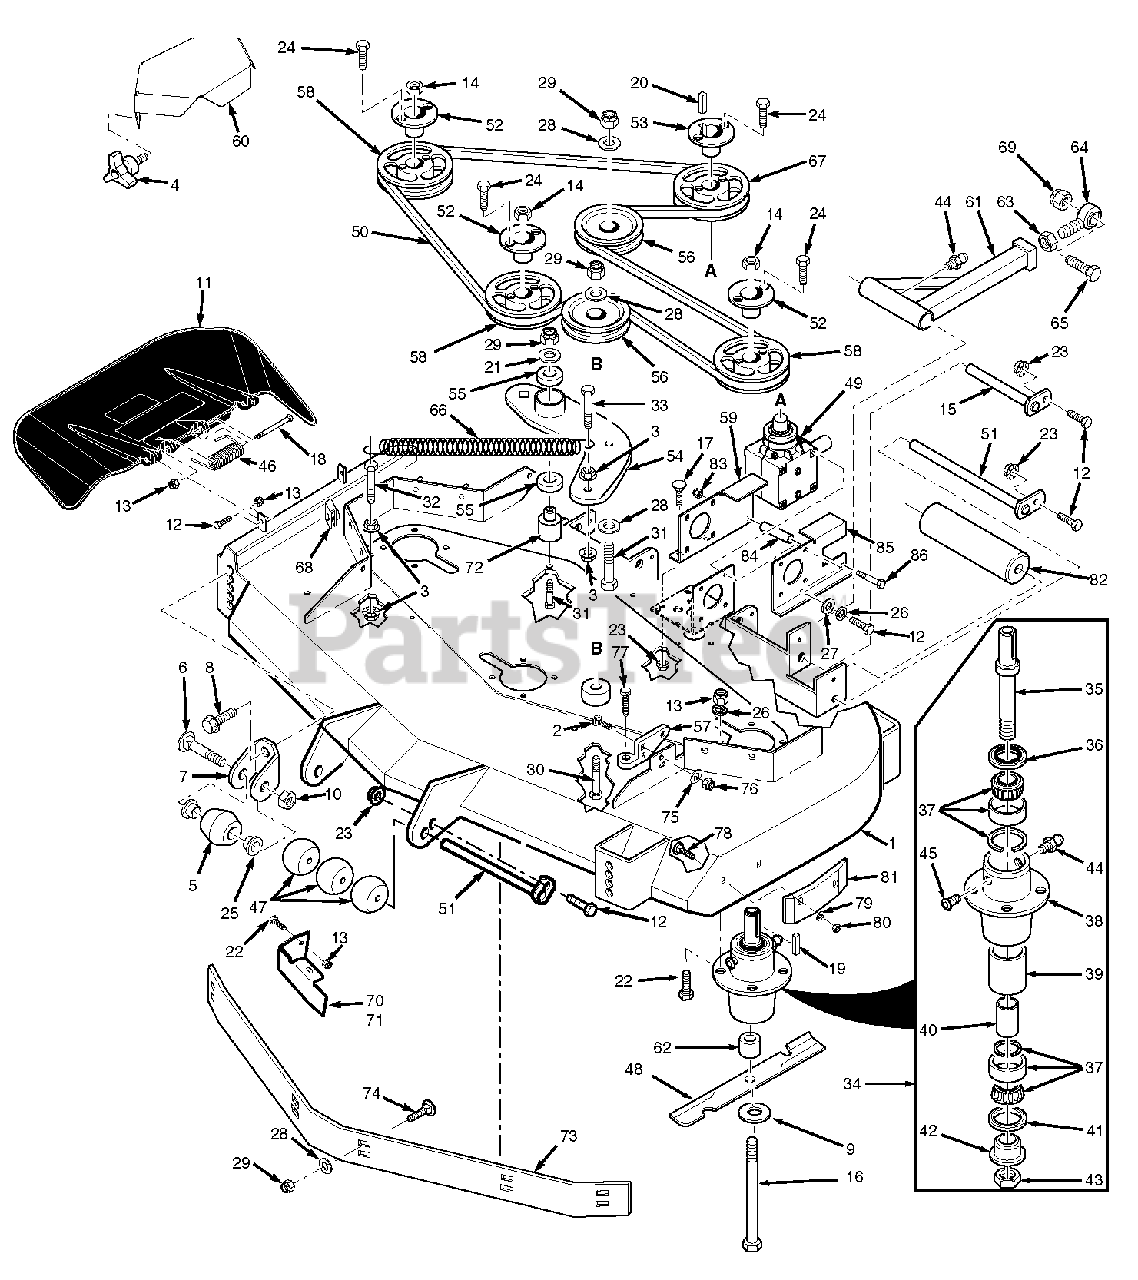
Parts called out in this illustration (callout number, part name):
1	Cutter Deck Velocity Plus
2	Bolt, Carriage 7/16-14 x 1-1/4"
3	Nut, Hex Serr. Flng 3/8-16
4	Wing nut, 3/8-16
5	Anti-Scalp Wheel
6	Bolt, Carriage 3/8-16 x 4"
7	Anti-Scalp Wheel Bracket
8	Bolt, Hex Serr. Flng 3/8-16 x 1"
9	Flatwasher, 5/8" Hardened
10	Locknut, 3/8-16 Center Lock
11	Discharge Chute Assembly
12	Bolt, Hex Head 5/16-18 x 1-3/4" - Front
12	Bolt, Hex Head 5/16-18 x 1-1/2" - Rear
13	Nut, Hex Elastic Stop 5/16-18 Grd 8
14	Nut, 5/8-11 UNC
15	Push Arm Shaft
16	Bolt, HH 5/8-11 x 9-1/2"
17	Bolt, Carriage 5/16-18 x 3/4"
18	Bolt, HH 5/16-18 x 4-1/2"
19	Key, 1/4 x 1/4 x 2"
20	Key, 1/4 x 1/4 x 1-1/4"
21	Flatwasher,3/8" (.39 x .938 x .105") HD
22	Bolt, HH 5/16-18 x 1-3/4"
23	Nut, Hex Serr. Flng 5/16-18
24	Bolt, HH 1/4-20 x 1" Grd 8
25	Bushing, .376" I.D. Oilite
26	Lockwasher, 5/16"
27	Flatwasher, 5/16" (.375 x .875 x .083")
28	Flatwasher, 3/8" (.391 x .938 x .105")
29	Nut, Hex Elastic Stop 3/8-16
30	Bolt, HH 3/8-16 x 3-1/4"
31	Bolt, HH 3/8-16 x 3"
32	Bolt, HH 3/8-16 x 1-1/2"
33	Bolt, HH 3/8-16 x 1-1/2" Grd 8
34	Spindle Assembly
35	Spindle Shaft
36	Seal, Top
37	Bearing Assembly
38	Spindle Housing
39	Spacer, Outside
40	Spacer, Inside
41	Seal, Bottom
42	Spindle Bushing, Bottom
43	Nut, Special 1-1/16-18
44	Grease Fitting
45	Relief Fitting, Tapered Spindle
46	Spring, Discharge Chute
47	Wheel, Anti-Scalp
48	Cutter Blade, 18"
49	Gearbox Assm, Deck Drive
50	Belt, Cutter Deck Drive
51	Roller Shaft
52	Tapered Hub, 1-1/8" Bore
53	Tapered Hub, 1" Bore
54	Idler Arm, Cutter Deck
55	Bearings, Ball
56	Pulley, Idler
57	Lever Assembly, Deck Level
58	Pulley, 5.75" O.D. (52")
59	Mounting Plate, RH Gearbox
60	Belt, Cover (52)
61	Pusharm
62	Spacer, Spindle Bottom
63	Nut, Hex Head 5/8-18 UNF
64	Rod End, 5/8" Male RH Thrd
65	Bolt, Hex Head 5/8-11 x 4-1/2"
66	Spring, Cutter Deck
67	Pulley, 6.95" O.D.
68	U-Nut, 3/8-16
69	Nut, Hex Elastic Stop 5/8-11
70	Discharge Baffle 52V
72	Pivot, Idler
73	Baffle, Custom Cut 52V
74	Bolt, Carriage 3/8-16 x 1"
75	Flatwasher, 7/16" (.500 x 1.25 x .083")
76	Nut, Elastic Stop 7/16-14
77	Bolt, Deck Adjust
78	Bolt, Carraige 5/16-18 x 3/4"
79	Flatwasher, 5/16"
80	Nut, Center Lock 5/16-18
81	Wear Pad
82	Wheel, Anti-Scalp
83	Nut, Elastic Stop 5/16-18
84	Spacer, Gearbox Mount
85	Mounting Plate, LH Gearbox
86	Bolt, HH 5/16-18 x 4-3/4"
